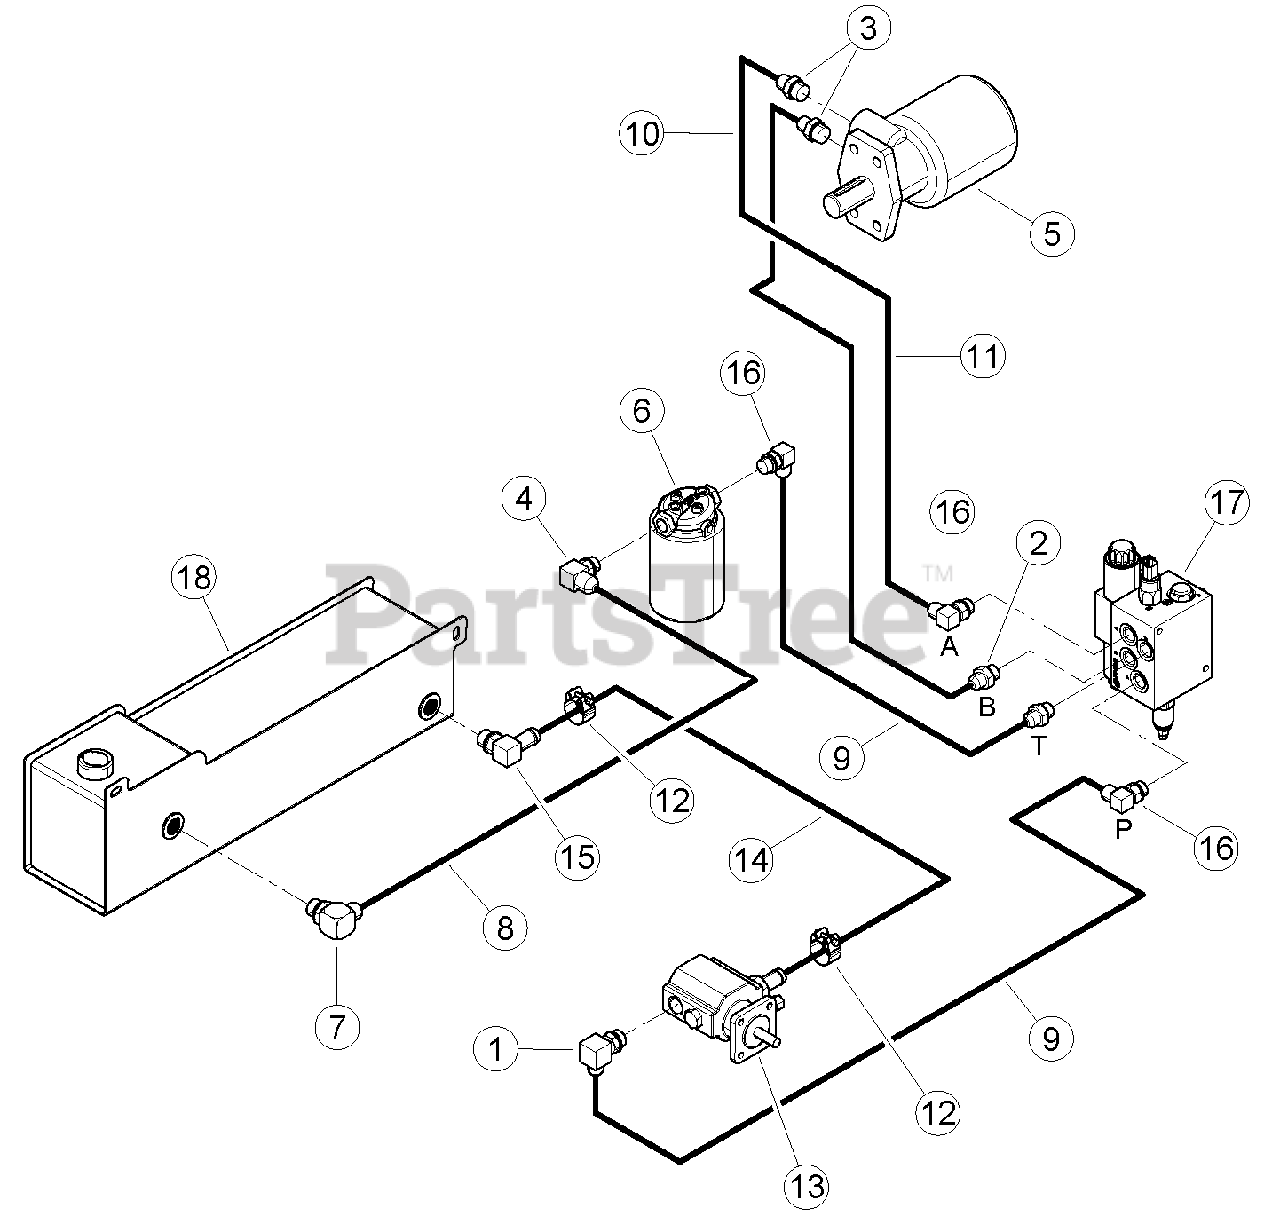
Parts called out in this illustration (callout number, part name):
1	ADAPTER, -10 MORING / -8 MJIC 90 DEG.
2	ADAPTER, -8 MORING / -8 MJIC
3	ADAPTER, -10 MORING / -8 MJIC
4	ADAPTER, -8 MORING / -10 MJIC 90 DEG.
5	MOTOR, 45 CU IN HYDRAULIC
6	ASSEMBLY, HYDRAUILC FILTER
7	ADAPTER, -10 MORING / -10 MJIC 90 DEG.
8	HOSE ASSEMBLY, -10 FMJ / -10 FMJ LD 90 DEG. X 21"
9	HOSE ASSEMBLY, -8 FMJIC / -8 FMJIC 90 DEG. X 21"
10	HOSE ASSEMBLY, -8 FMJIC / -8 FMJIC 90 DEG. X 61"
11	HOSE ASSEMBLY, -8 FMJIC / -8 FMJIC X 61"
12	CLAMP, 1-5/32 TO 7/32 OD RANGE T-BOLT
13	PUMP, 2 STAGE CW HI/LO 0.605 DISP.
14	HOSE, .75 ID X 24 IN. 100R4 HYD
15	ADAPTER, -10 MORING / .75 90 DEG. HOSE
16	ADAPTER, -8 MORING / -8 MJIC 90 DEG.
17	ASSEMBLY, HYDRAULIC FEED FLOW VALVE
18	WELDMENT, HYDRAULIC TANK
